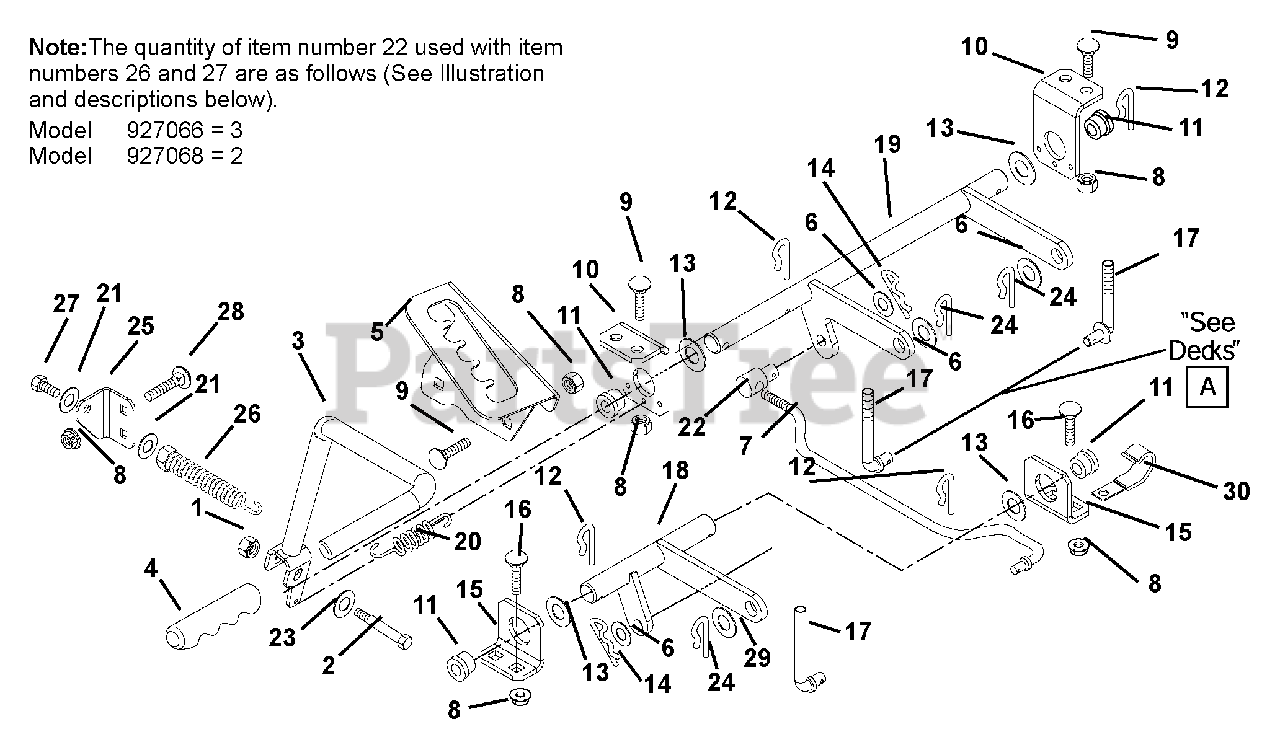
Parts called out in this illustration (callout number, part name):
1	Nut, Locking Top Flange .31-18
2	Bolt, 1.25 Socket Shoulder Plain
3	Weldment, Lift Handle
5	Detent Plate
6	Washer, Flat Steel .511 x 1.44 x .125
7	Rod, Deck Lift
8	Nut, Locking Top Flange .38-16
9	Bolt, Round Head Square Neck .38-16 x .75 Grade 5
10	Bracket, Lift
11	Bushing, Flange .75 x 1.00 x .625 x 1.25
12	Pin, Spring Clip
13	Washer, Flat Steel .563 x 1.38 x .109
14	Pin, Hair #16
15	Bracket, Deck Pivot
16	Bolt, Round Head Square Neck .38-16 x 1.00 Grade 5
17	Rod, Link (066, 068)
18	Weldment, Front Lift (066, 068)
19	Weldment, Lift
20	Spring, Extension
21	Washer, Flat Steel .43 x 1.00 x .16 (066)
21	Washer, Flat Steel .43 x 1.00 x .16 (068)
22	Pivot, Rod
23	Washer, Flat Steel .43 x 1.00 x .160
24	Clip, Spring
25	Bracket, Spring Anchor
26	Spring, Tension .195 x 1.15 x 5.50
27	Bolt-Hex .38-16 x 1.50 Grade 5
28	Bolt, Round Head Square Neck .38-16 x .75 Grade 5
29	Washer, Flat Steel .563 x 1.38 x .109
